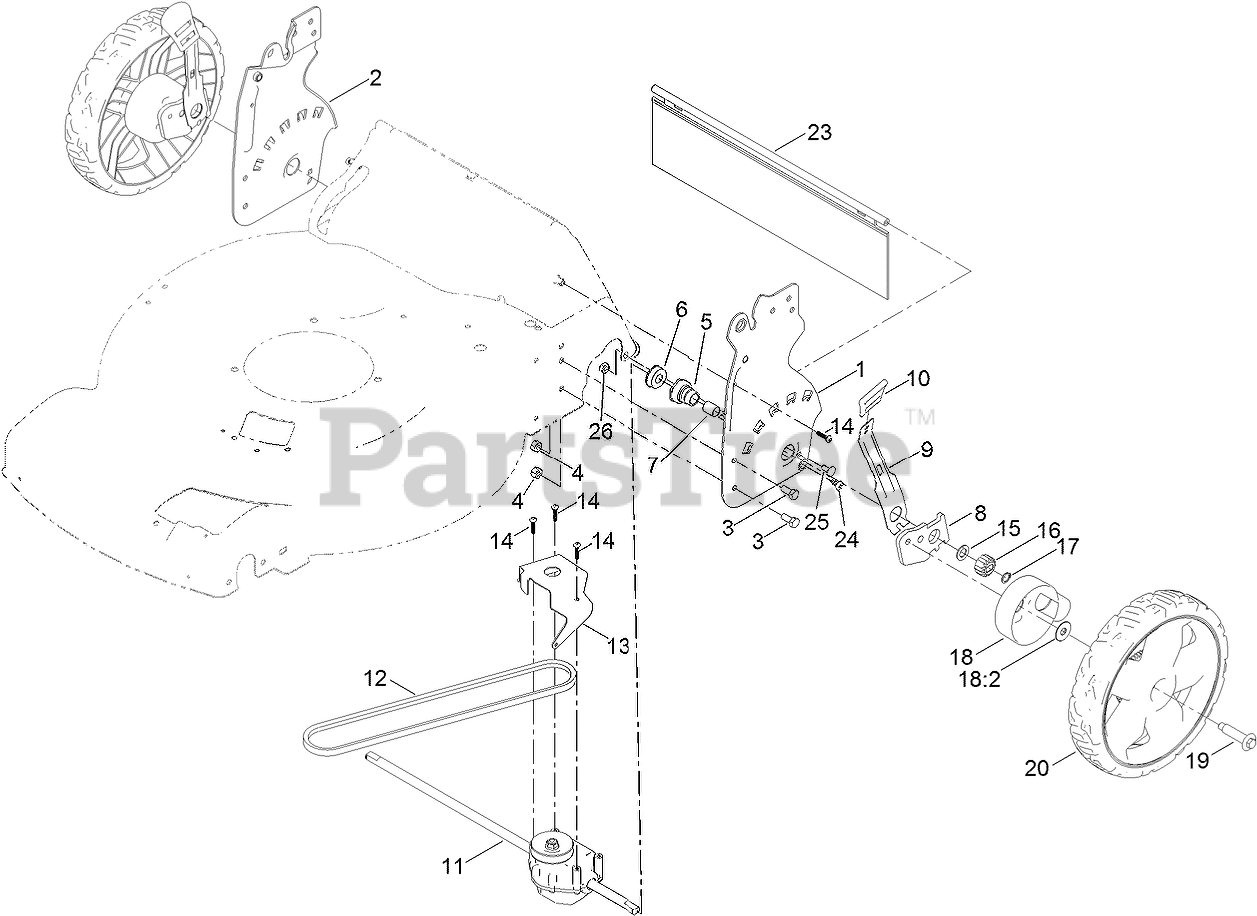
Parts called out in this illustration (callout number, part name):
1	ASM-PLATE, HOC (LH)
2	ASM-PLATE, HOC (RH)
3	SCREW-HH
4	NUT-LOCK, NI
5	RETAINER-BUSHING, HOC
6	BEARING-BALL
7	BUSHING-SLEEVE
8	ARM-PIVOT, REAR
9	ARM-SPRING
10	KNOB-HOC
11	TRANSMISSION-RWD (6:1)
12	BELT-V
13	BRACKET-TRANSMISSION
14	SCREW-PLASTITE
15	WASHER-THRUST
16	GEAR-PINION, 15T
17	RING-RETAINING
18	GEAR COVER ASM
18:2	WASHER-STEPPED
19	BOLT-SHOULDER
20	WHEEL GEAR ASM
23	SHIELD-TRAILING
24	SCREW-PTH
25	SCREW-CARR
26	NUT-LOCK, NI
